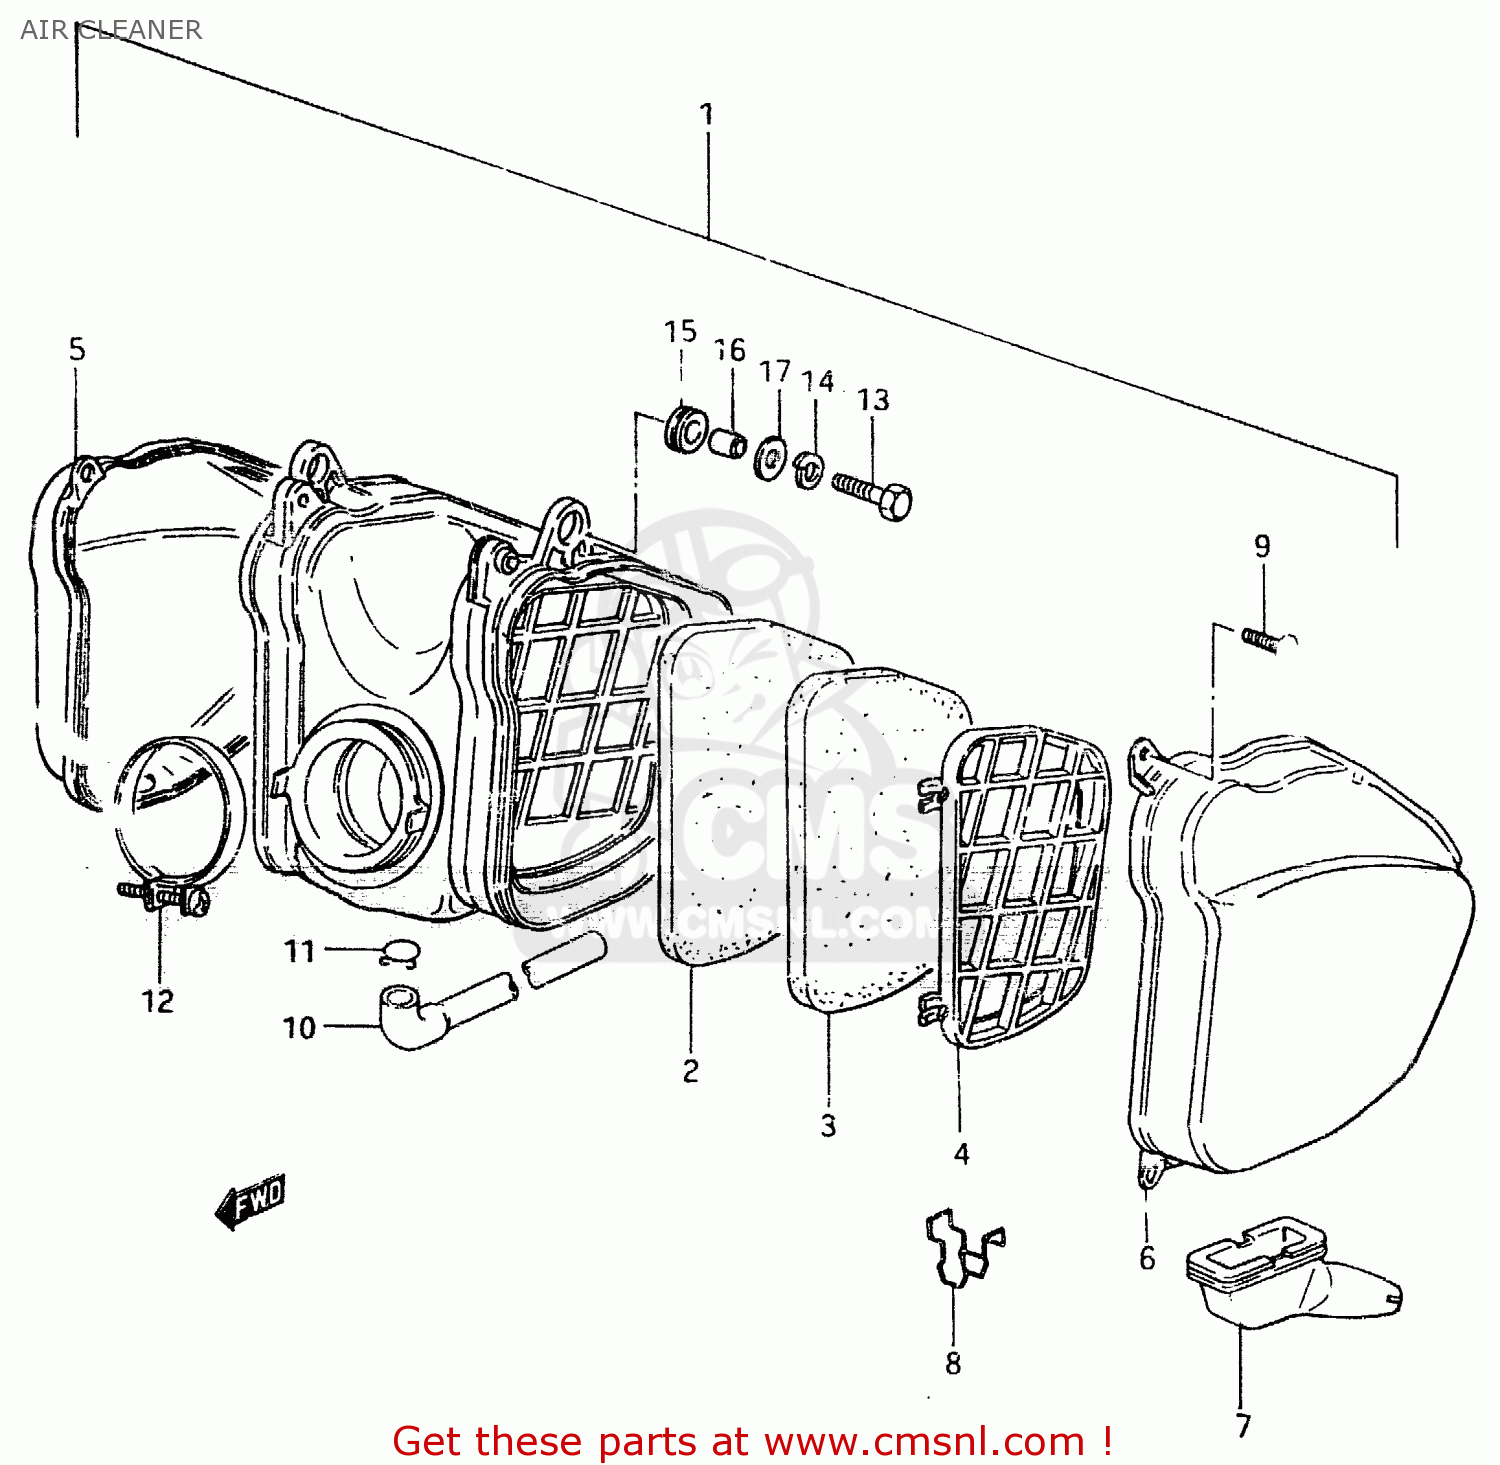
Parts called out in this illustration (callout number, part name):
1	CLEANER ASSEMBLY,AIR
2	FILTER
3	FILTER,2ND
4	HOLDER,AIR CLEANER,LEFT
5	CAP,AIR CLEANER,RIGHT
6	CAP,AIR CLEANER,LEFT
7	DRAIN TUBE
8	DRAIN STOPPER
9	SCREW
10	DRAIN TUBE
11	CLIP
12	CLAMP
13	BOLT
14	LOCK WASHER
15	CUSHION
16	SPACER (7X9X7)
17	WASHER
